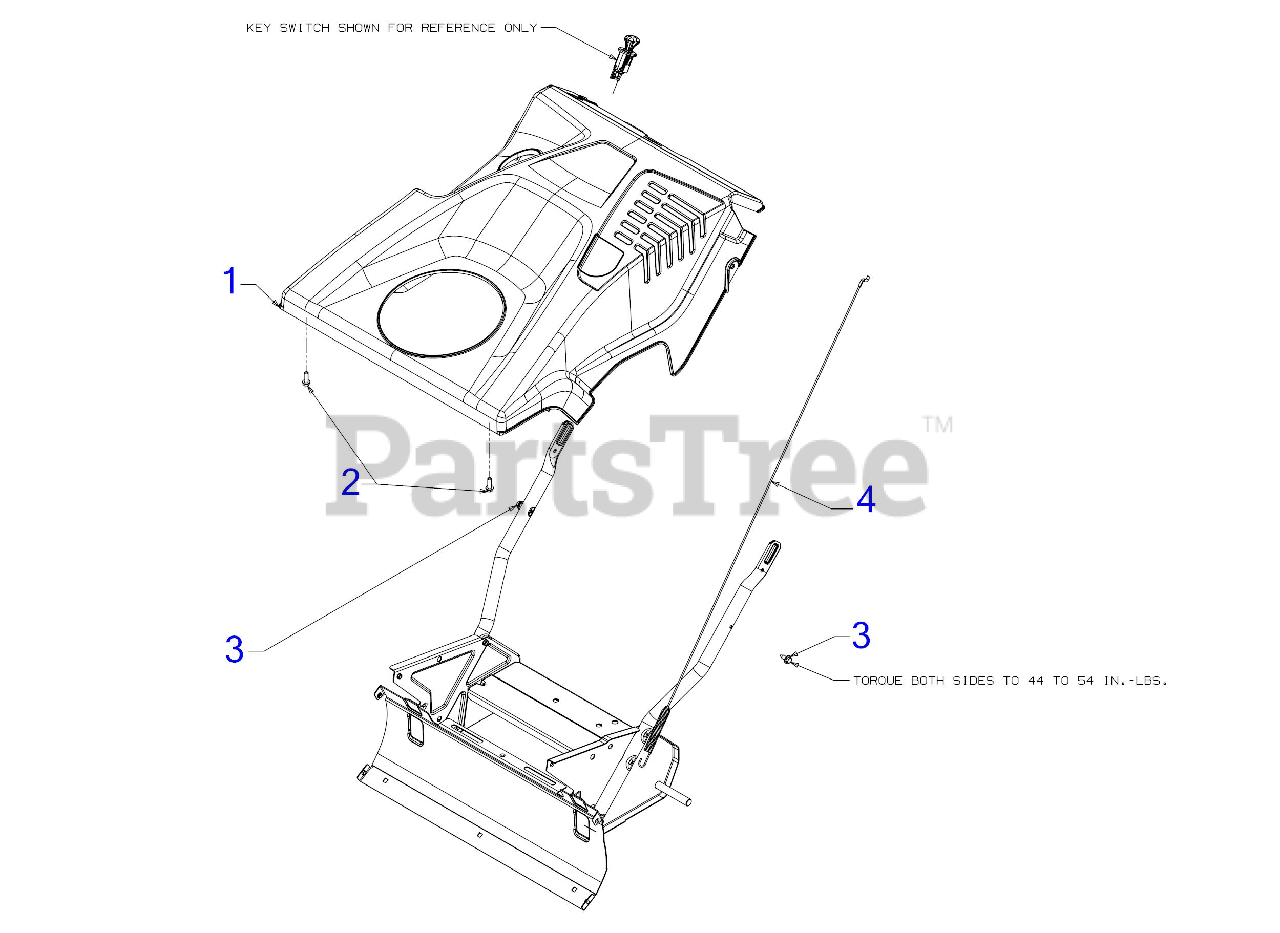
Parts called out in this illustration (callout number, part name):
1	COVER ASSEMBLY
2	SCREW 1/4-15 x .750
3	SCREW 1/4-20X.625
4	CLUTCH CABLE 35.03"
